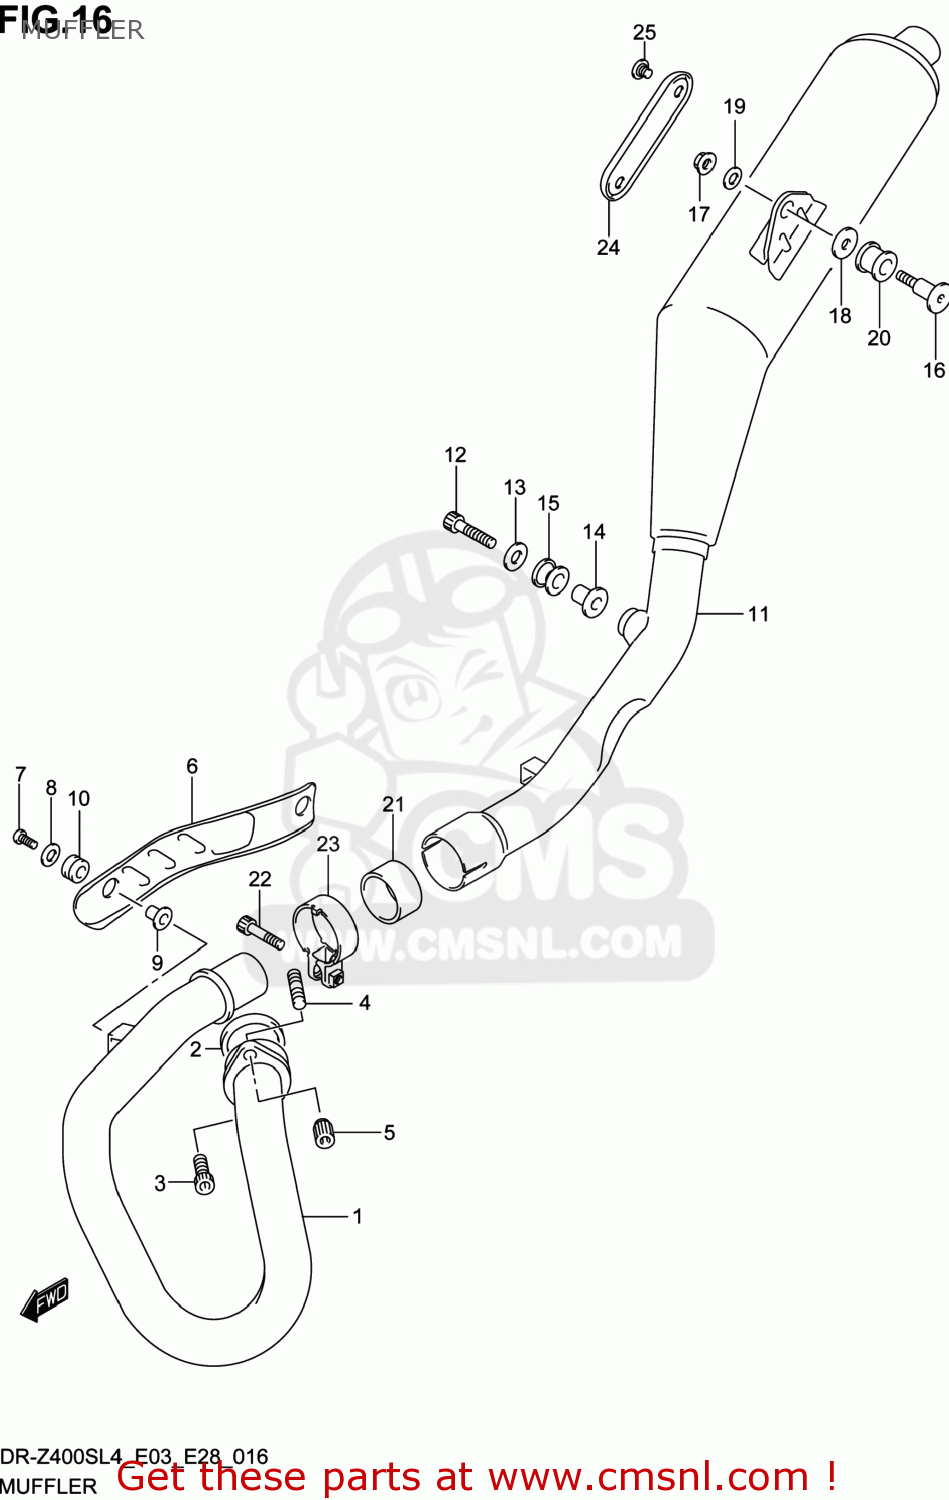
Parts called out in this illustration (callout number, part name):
1	PIPE,EXHAUST
2	GASKET,EXHAUST PIPE
3	BOLT
4	BOLT,STUD
5	NUT
6	COVER,EXHAUST PIPE
7	SCREW(6X16)
8	WASHER(6.5X18X1)
9	SPACER,EXHAUST PIPE COVER
10	CUSHION
11	BODY,MUFFLER
12	BOLT(8X35)
13	WASHER(8.5X26X1.6)
14	SPACER(8.6X12X17.5)
15	CUSHION
16	BOLT,MUF SPRT RR
17	NUT
18	WASHER(8.5X30X2.3)
19	WASHER
20	CUSHION
21	CONNECTOR,MUFFLER JOINT
22	BOLT
23	CLAMP,MUFFLER CONNECTOR
24	COVER,MUFFLER
25	SCREW
